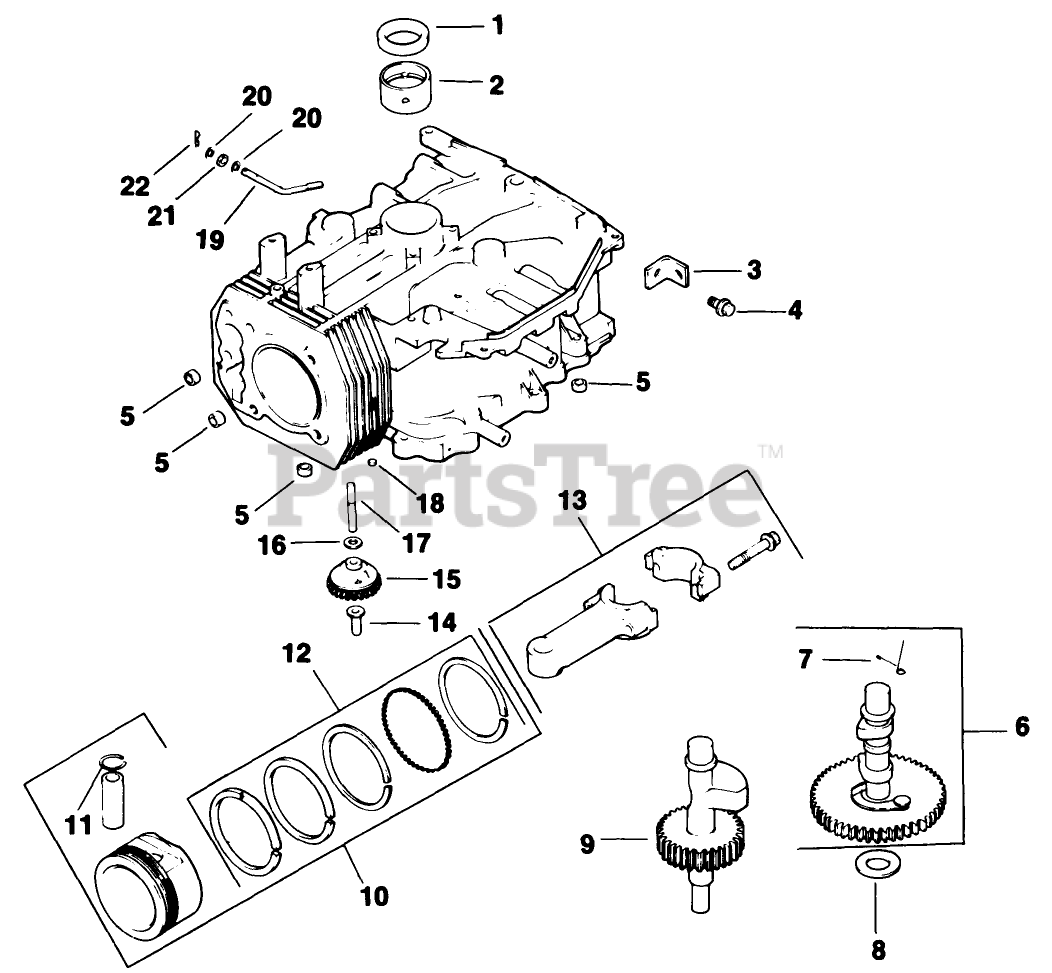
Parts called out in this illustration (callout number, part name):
1	Seal-Crankshaft (Only On: 72042, 72043, 72062, 72063)
2	Bearing-Crankshaft
3	Strap-Lifting (Only On: 72042,72043,72062,72063)
5	Pin-Dowel
6	Camshaft Assembly
7	Spring-Actuating (Only On: 72042,72043,72062,72063)
8	Shim-Camshaft
9	Shaft-Balance
10	Piston W/Ring Set (Std.)
11	Retainer-Piston Pin (Only On: 72042, 72043,72062,72063)
12	Ring Set STD (Only On: 72042,72043,72062,72063)
13	Connecting Rod STD (Only On: 72042, 72063, 72062, 72043)
14	Pin-Governor
15	Gear-Governor ASM (Only On: 72042, 72063, 72062, 72043)
17	Shaft-Govenor Gear
19	Shaft-Governor Cross (Only On: 72042, 72063, 72062, 72043)
20	Washer-Governor Shaft (Only On: 72042, 72063, 72062, 72043)
21	Seal
22	Pin-Hitch
